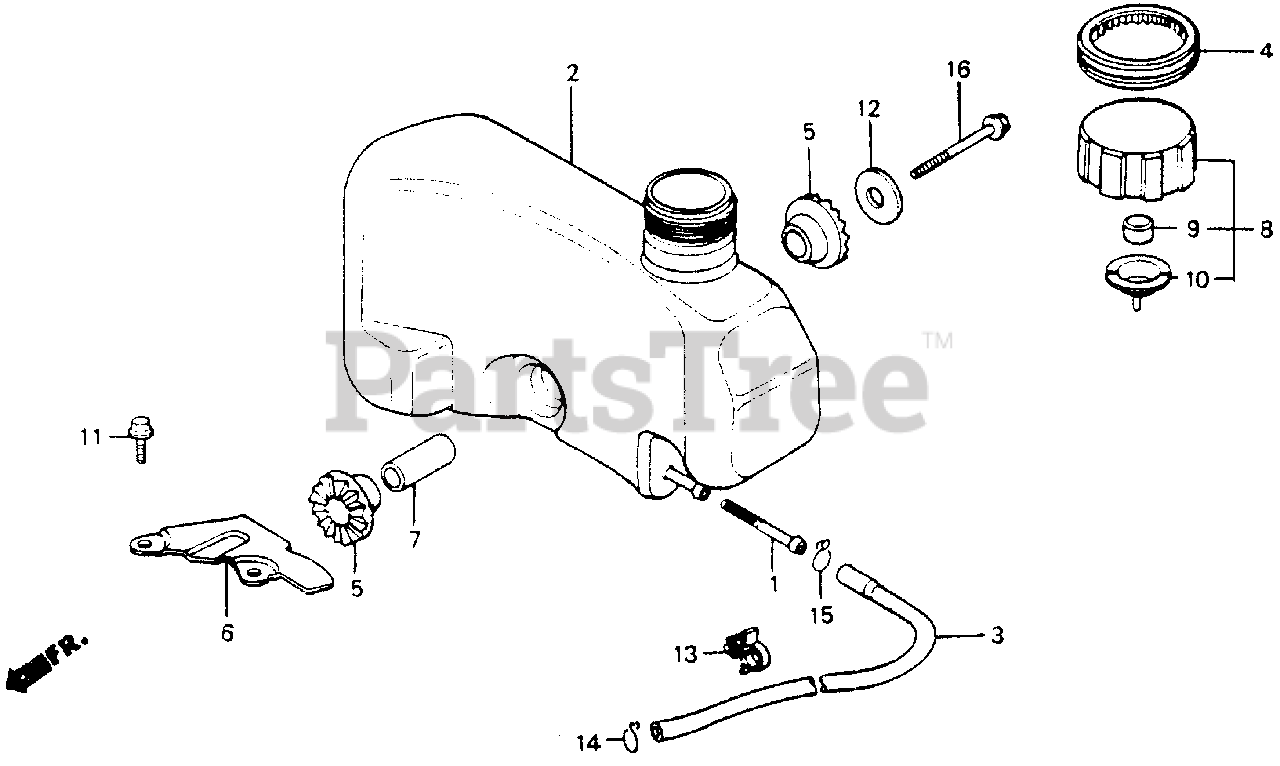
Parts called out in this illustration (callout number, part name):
1	FILTER, FUEL
2	TANK, FUEL
2	TANK, FUEL (USA)
3	TUBE, FUEL
4	RUBBER, TANK MOUNTING
5	RUBBER B, TANK MOUNTING
6	STAY, TANK
7	COLLAR, TANK SETTING
8	CAP ASSY., FUEL TANK
9	SPONGE, FUEL CAP BREATHER
10	GASKET, FUEL CAP
11	BOLT, FLANGE (6X14)
12	WASHER, TANK MOUNTING
13	CLIP B, CABLE
14	CLIP, TUBE (B8)
15	CLIP, TUBE (C11)
16	BOLT, FLANGE (8X50)
